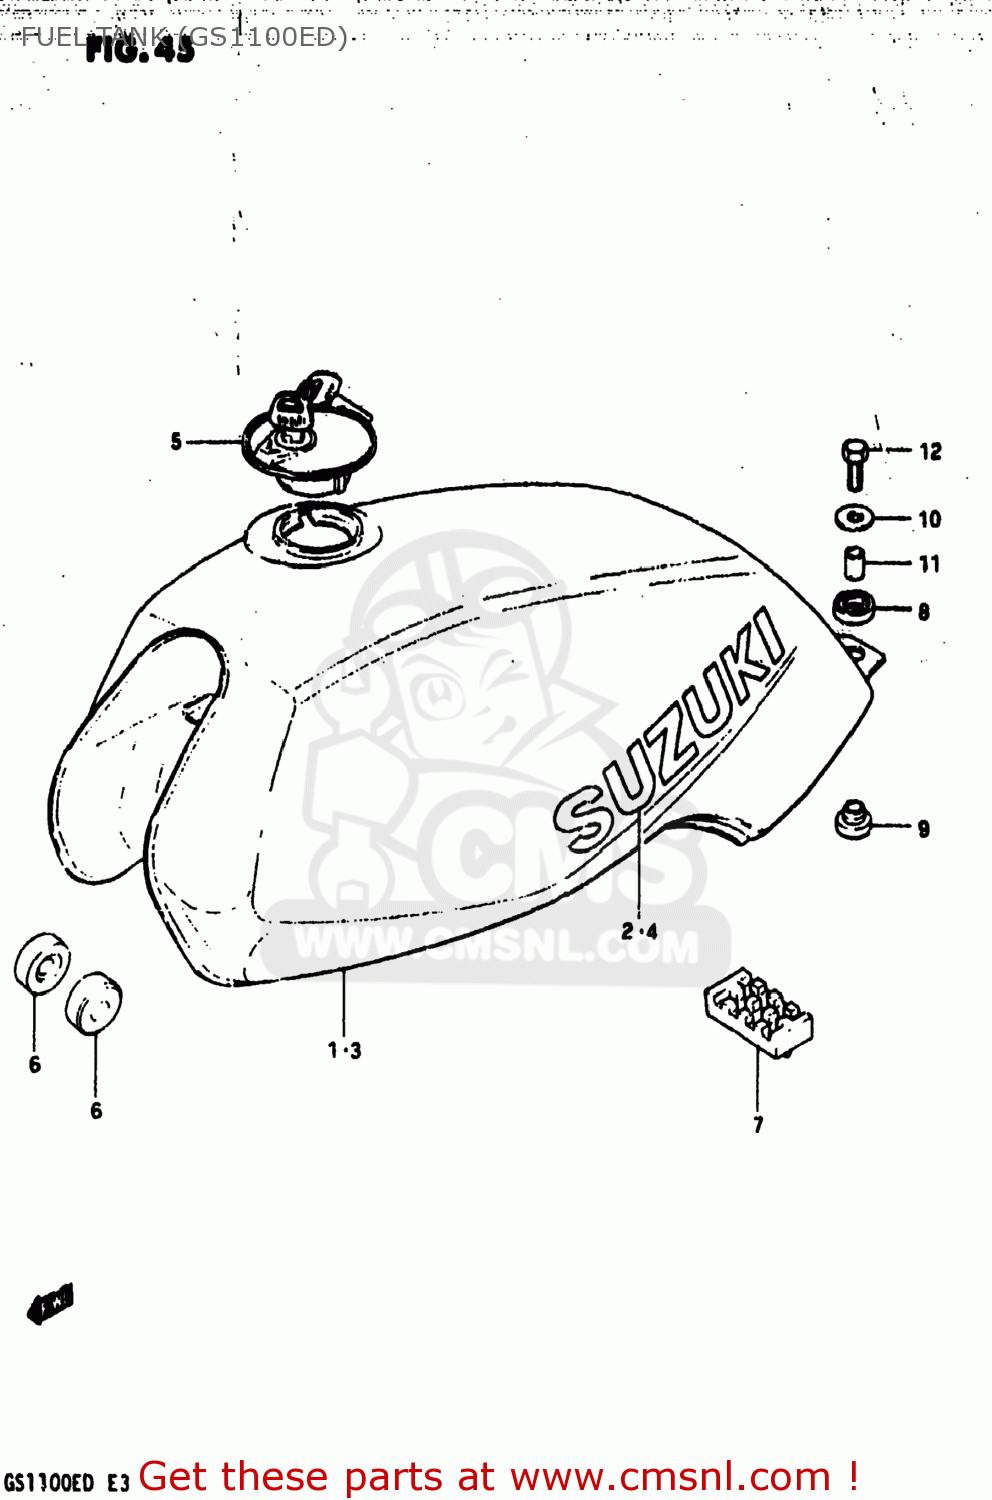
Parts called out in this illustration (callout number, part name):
1	TANK ASSEMBLY,FUEL
2	EMBLEM
3	TANK ASSEMBLY,FUEL
4	EMBLEM
5	CAP SET,FUEL TANK
6	CUSHION
7	CUSHION,FUEL TANK CTR
8	CUSHION
9	CUSHION
10	WASHER (6.5X24X1.6)
11	SPACER
12	BOLT
